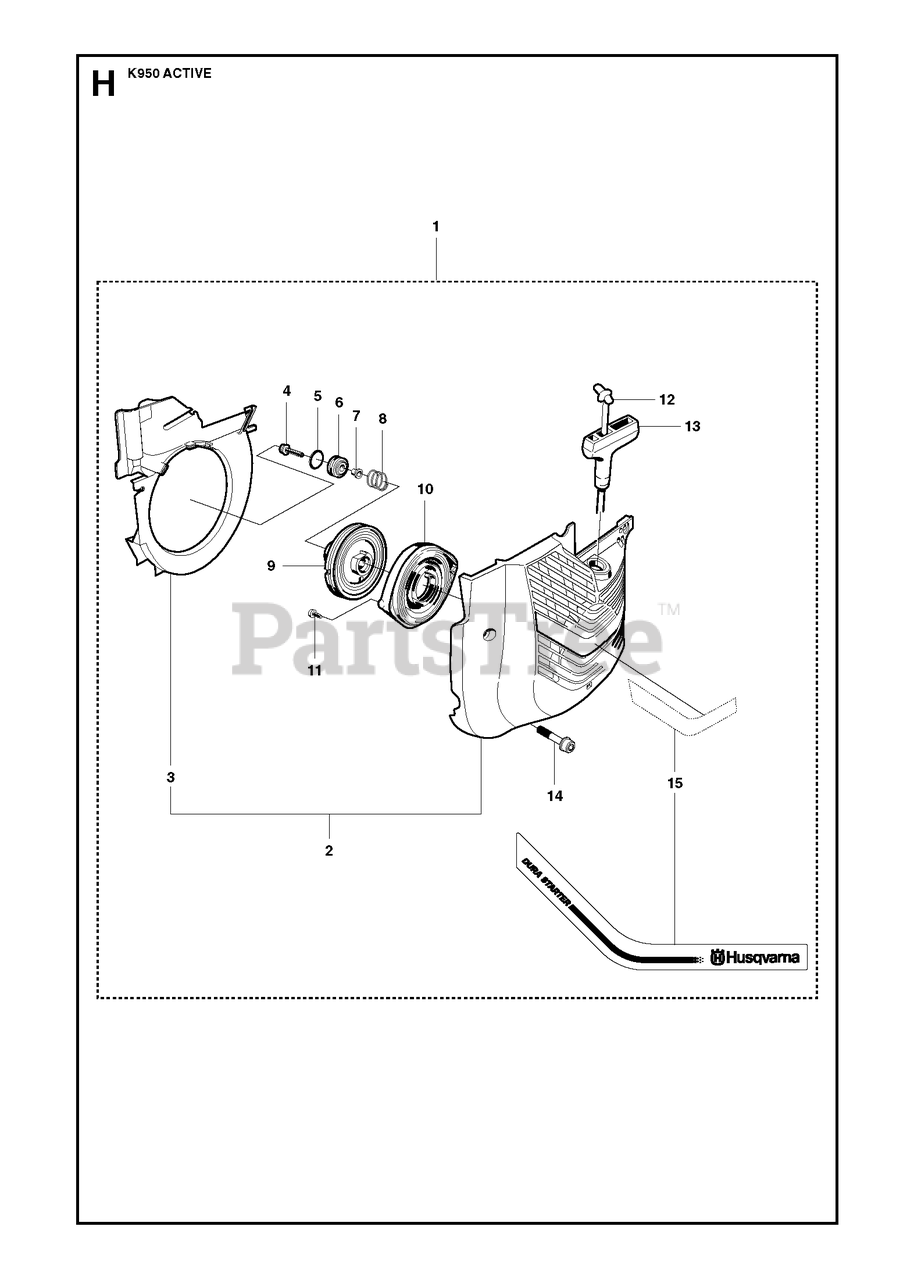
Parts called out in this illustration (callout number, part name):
4	SCREW IHSCFT
6	GROMMET
7	SPACING SLEEVE
8	COMPRESSION SPRING
9	STARTER PULLEY
10	RECOIL SPRING
11	SCREW CCRPANT
12	STARTER CORD50 m. coil
13	STARTER HANDLE
14	SCREW IHSCFMO
